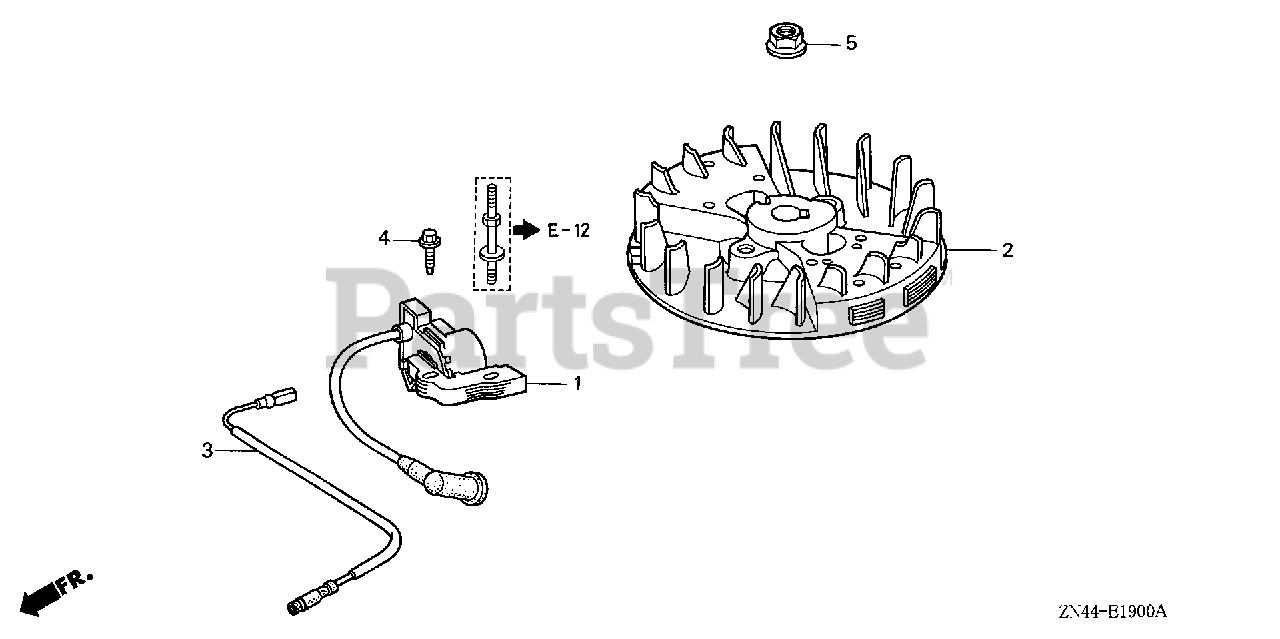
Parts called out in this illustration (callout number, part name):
1	COIL ASSY., IGNITION
2	FLYWHEEL
3	WIRE, STOP SWITCH
4	BOLT, FLANGE (5X20)
5	NUT, FLANGE (10MM)
